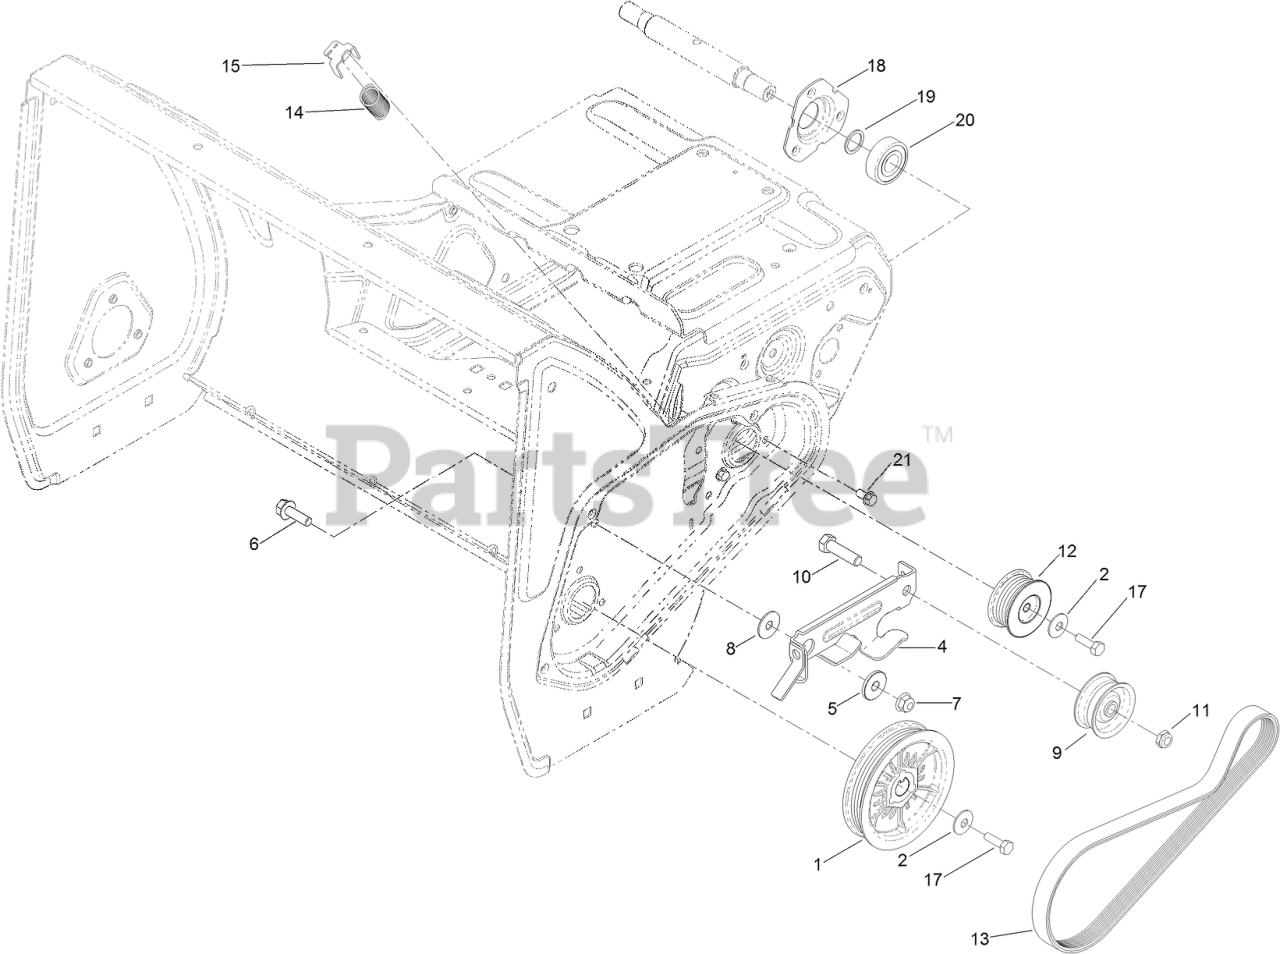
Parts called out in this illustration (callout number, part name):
1	PULLEY-ROTOR
2	WASHER-BELLEVILLE
4	ARM-CLUTCH, ROTOR
5	BUSHING-IDLER
6	SCREW-HHF
7	NUT-HF, NI
8	WASHER
9	PULLEY-IDLER, FLAT
10	SCREW-HH
11	NUT-LOCK, NI
12	PULLEY-JACKSHAFT, ROTOR
13	BELT-POLY V
14	SPRING-EXTENSION
15	CLIP-SPRING, BRAKE
17	SCREW-HH
18	FLANGE-BEARING
19	WASHER-THRUST
20	BEARING-BALL
21	SCREW-HWH
